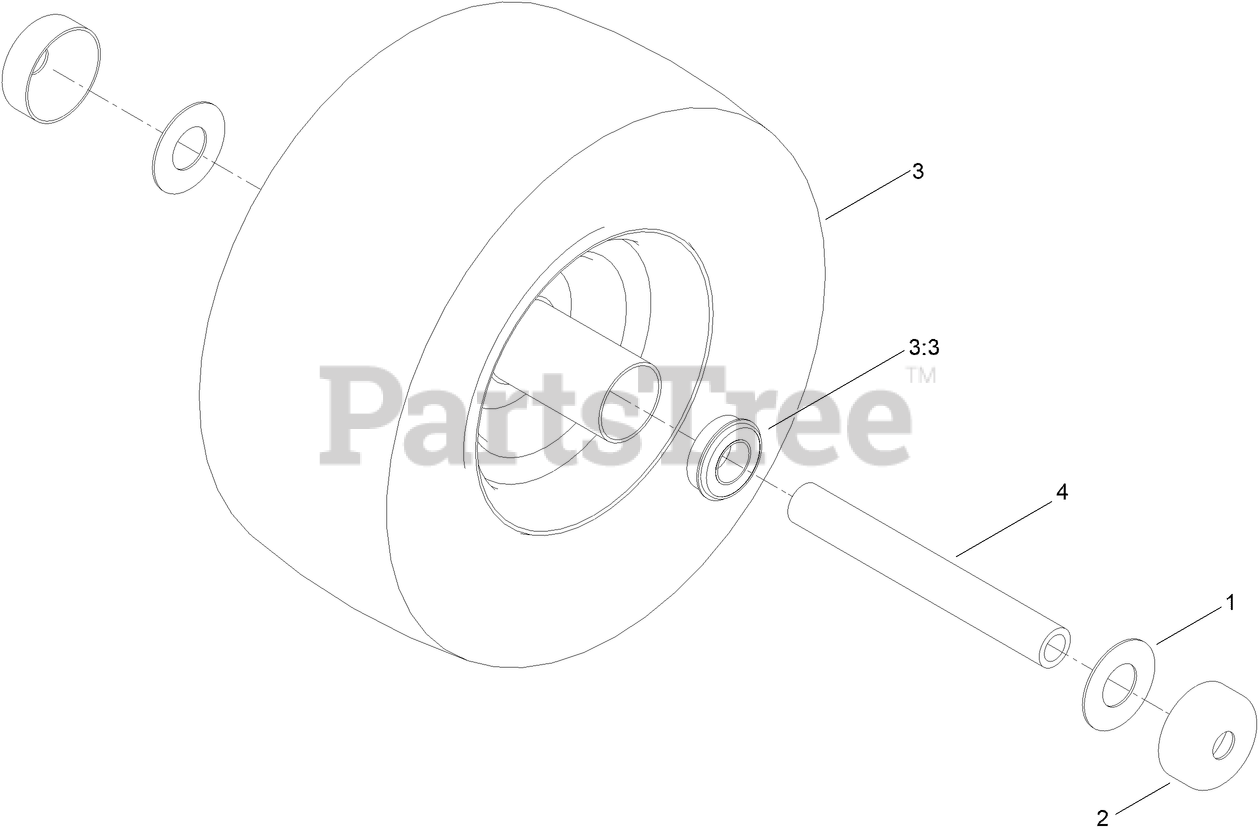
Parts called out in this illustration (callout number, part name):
1	WASHER
2	GUARD-SEAL
3	TIRE AND WHEEL ASM
3:3	BEARING
4	SPACER-SPANNER
